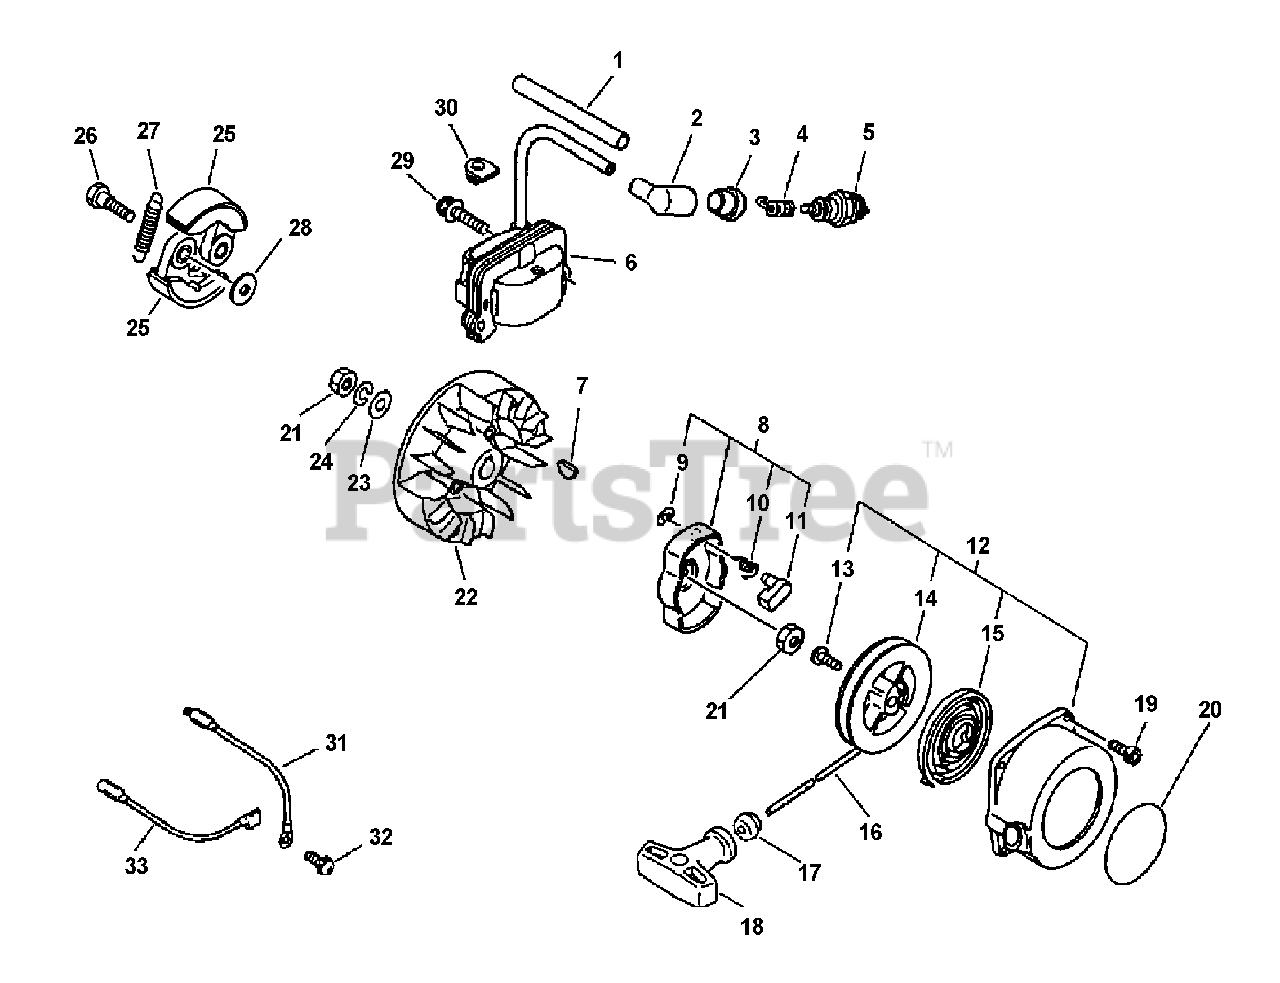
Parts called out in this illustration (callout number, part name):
2	CAP, SPARK PLUG
3	COVER, PLUG CAP
4	TERMINAL, SPARK PLUG CAP
5	SPARK PLUG -- BPM-7A
5	SPARK PLUG -- BPMR-7A
6	COIL, IGNITION
8	STARTER PAWL ASSY
9	RING, RETAINING - 4
10	SPRING, RETURN
11	PAWL, STARTER
12	STARTER ASSY
14	REEL, ROPE
15	SPRING, REWIND
16	ROPE, STARTER
17	GUIDE, ROPE
18	GRIP, STARTER
19	SCREW - 4X14
20	LABEL - ECHO
22	FLYWHEEL
23	WASHER - 8
24	LOCKWASHER - 8
25	SHOE, CLUTCH
26	BOLT, CLUTCH
27	SPRING, CLUTCH
28	WASHER - 6
29	SCREW - 5X20
30	GROMMET
31	LEAD - GROUND
32	SCREW - 5X10
33	LEAD - IGNITION
